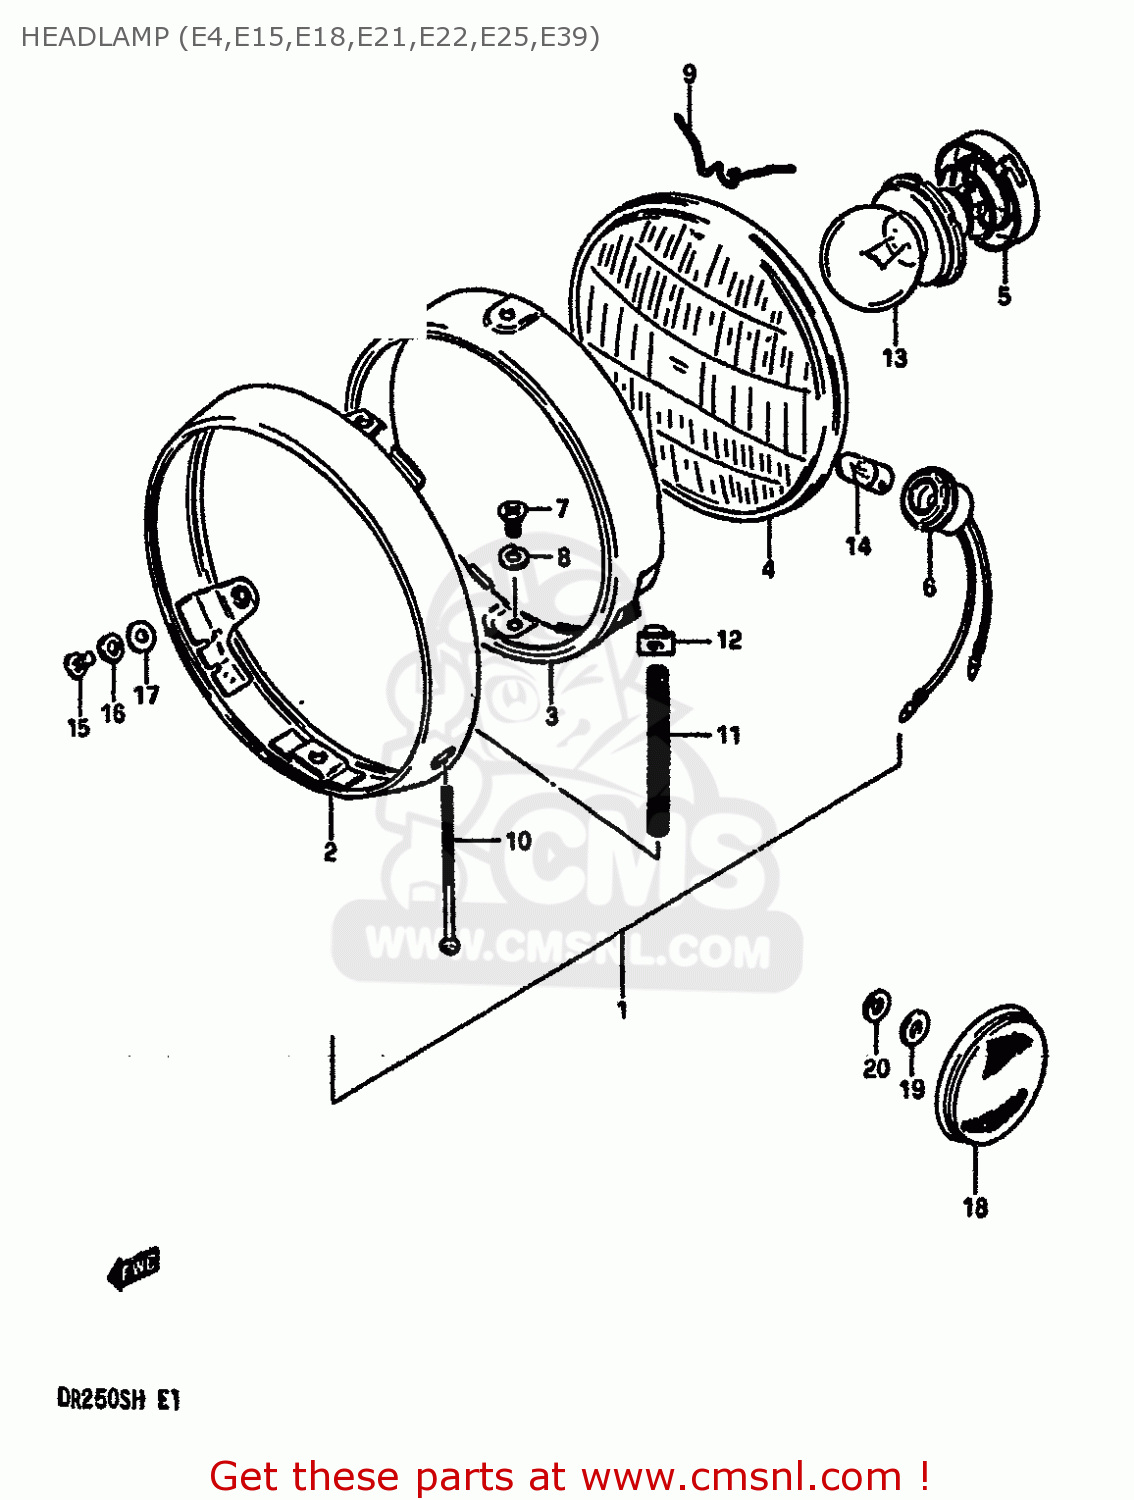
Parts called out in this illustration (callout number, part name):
1	HEADLAMP ASSY
2	RIM,HEADLAMP
3	RETAINER
4	LAMP UNIT
5	SETTER,BULB
6	SOCKET
7	SCREW
8	LOCK WASHER
9	SPRING
10	SCREW
11	SPRING
12	NUT
13	BULB(12V45/40W)
14	BULB(12V4W)
15	SCREW
16	LOCK WASHER
17	WASHER
18	REFLEX REFLECTOR,FR
19	LOCK WASHER
20	WASHER
